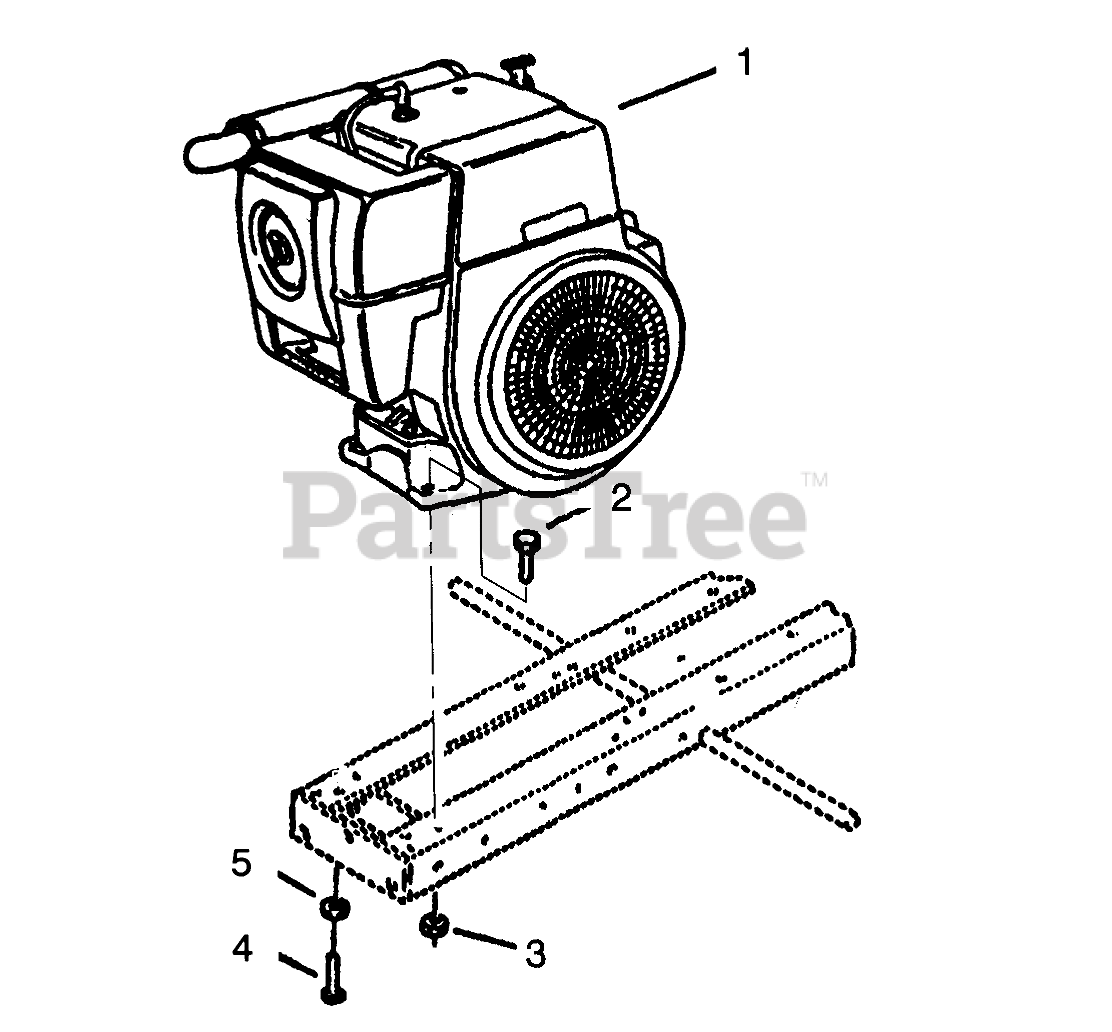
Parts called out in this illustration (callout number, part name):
1	Engine-12 Hp Kohler
2	SCREW-HH
3	NUT-LOCK, NI
4	SCREW-HH
5	WASHER-LOCK
